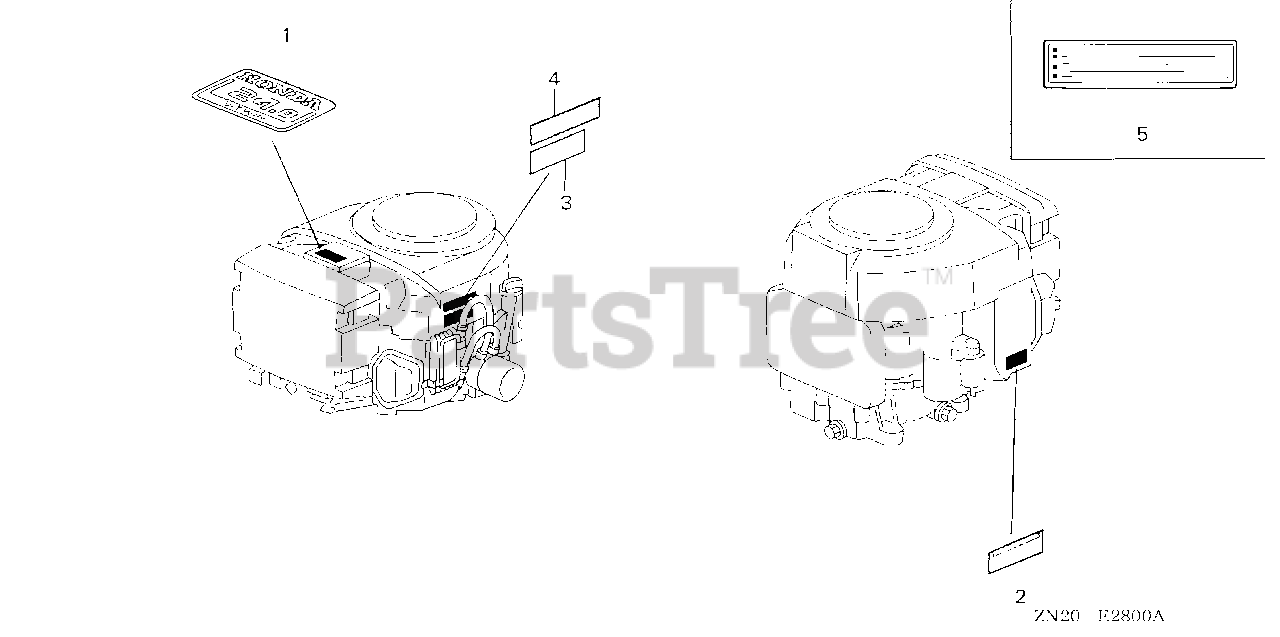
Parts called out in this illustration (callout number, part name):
1	EMBLEM (24.0)
1	EMBLEM (GX670)
2	LABEL, SPECIFICATION (GXV670)
5	LABEL, CAUTION (ENGLISH, ETC.)
